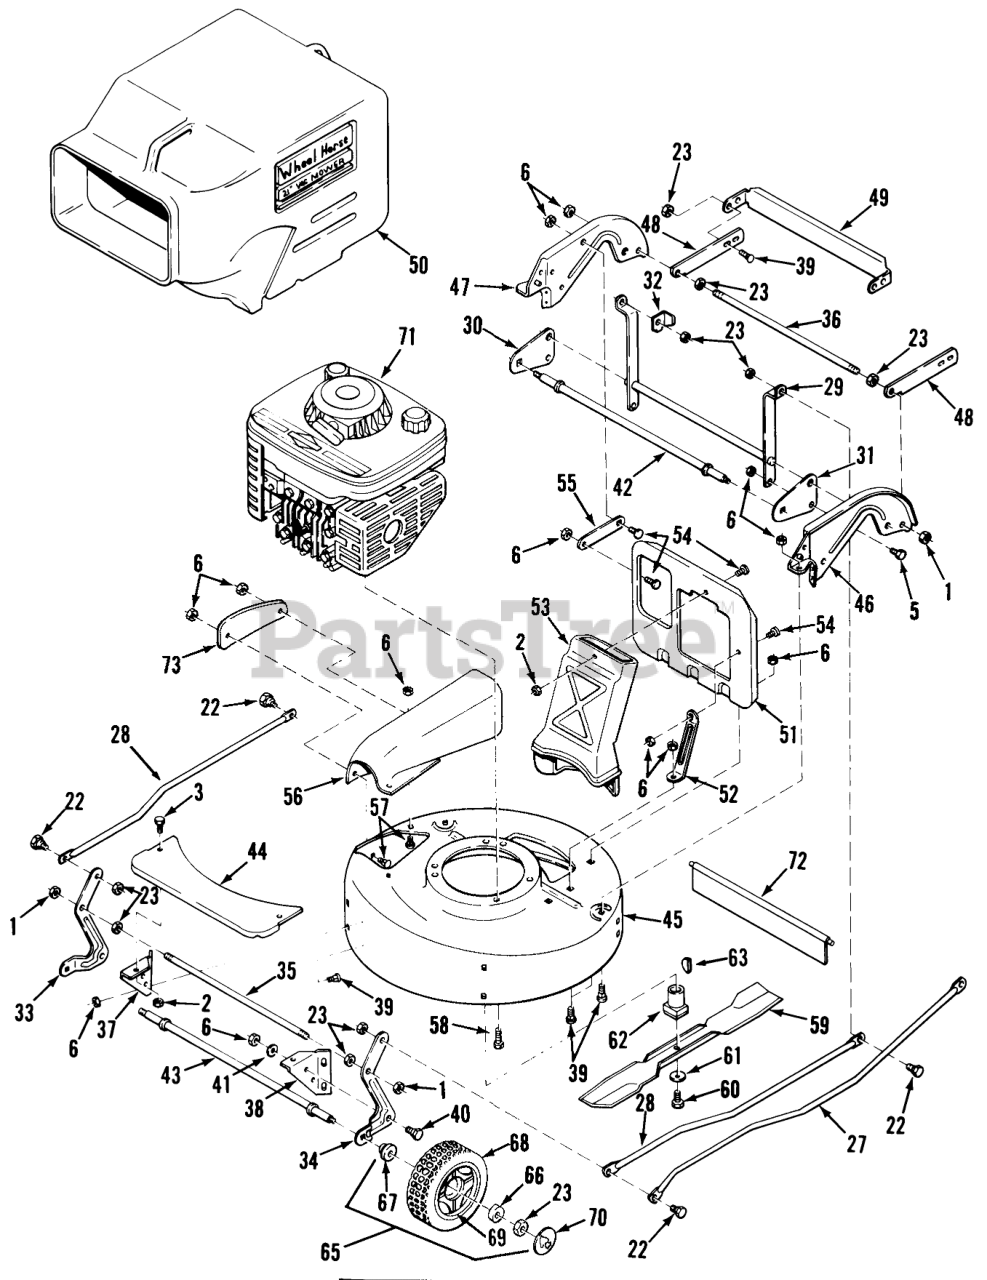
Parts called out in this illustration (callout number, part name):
1	NUT-JAM(7/16-14)
2	Hex Nut 1/4-28
3	Hex Bolt 1/4-28 x 5/8
5	Screw
6	Flanged Nut
22	SHOULDER BOLT
23	Hex Nut 7/16-14
27	Height Adjust Main Control Rod
28	Height Adjust Short Control Rod
29	Height Adjust Rear BRKT
30	Plate-Rear Axle RH
31	REAR AXLE PLATE (LH)
32	HGT ADJ INDICATOR
33	HGT ADJ BRACKET
34	BRKT-LH Front Height Adjust
35	FRONT & REAR TIE ROD
36	Rear Tie Rod 7/16-14 x 16 9/16
37	RIGHT FRONT MTG BRKT
38	BRKT-MTG LH Front
39	CARRIAGE BOLT -4
40	Shoulder Bolt 5/16-18 x 5/8
41	WASHER 5/16 SAE
42	Rear Axle 7/16-14 X 21
43	Front Axle 7/16-14 x 21 1/4
44	Front Support Panel
45	Mower Deck
46	Left Wheel Skirt
47	RIGHT WHEEL SKIRT
48	Catcher Support Arm
49	Catcher Support Rear Bracket
50	Grass Catcher
51	Grass Catcher Plate
52	PLATE
53	Air Return Duct
54	Special Hd Bolt 1/4-28 x 7/16
55	CATCHER PLATE
56	Chute
57	Bolt
58	Self Tapping Hex Bolt 3/8 X 1
59	MOWER BLADE
60	Blade Bolt 3/8-24 X 2
61	Blade Washer 3/8 Special
62	Blade Drive Hub
63	WOODRUFF KEY
65	ASSY WHEEL
66	Wheel Bearing-Outside
67	Wheel Bearing-Inside
69	Wheel Rim
70	HUB CAP
71	Engine-Briggs & Stratton 3.5 HP (model 90702 type 900613B)
72	Rear Protective Guard
73	Discharge Chute Plate
